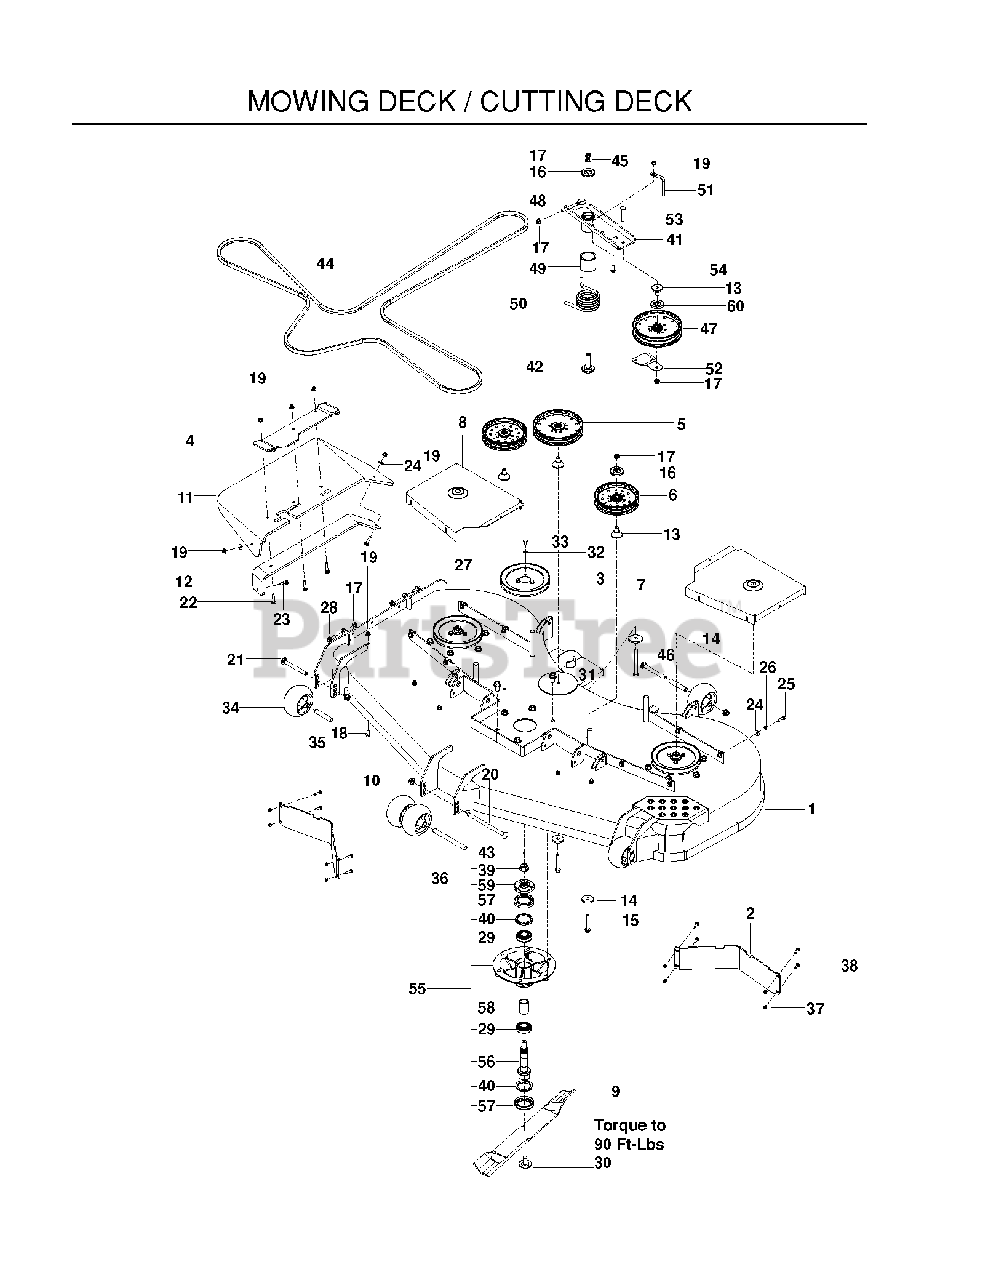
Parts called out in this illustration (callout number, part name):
1	DECK.SVC.W/DECALS.72.ORANGE.HU
2	BAFFLE, DIVERTER 72" BLACK
3	PULLEY - 7.50
4	BRKT - CHUTE MTG BLACK
5	PULLEY - 7" NARROW
6	PULLEY IDLER, 6" NARROW
7	SHIELD, BELT 72 R.H. ORANGE
8	SHIELD, BELT 72 LH ORANGE
9	BLADE OEM - 25"
10	NUT, 1/2-13 HEX FLG NYLOC ZD
11	CHUTE, DISCHARGE 60-72
12	BRKT - CHUTE SUPPORT BLACK
13	BEARING, IDLER ARM
14	SPINDLE WASHER
15	HHFS 3/8-16 X 2 3/4
16	DUST SHIELD
17	NUT 3/8-16 HEX FLG NYLOC ZD
18	HHFS 5/16-18 X 3/4
19	5/16-18 NYLOC FLANGE NUT
20	RHSNB 1/2-13 X 8 GR5 ZD
21	RHSNB 1/2-13 X 4.75 GR5 ZD
22	RHSNB 5/16-18 X 1-1/2 GR 5 ZD
23	BOLT, CARRIAGE 5/16X1-1/4
24	WASHER 5/16 FLAT
25	HCS 5/16C X 1
26	WASHER 5/16 LOCK
27	U-CLIP 5/16-18 NUT RETAINER
28	HHFS 3/8-16 X 1 GRD 5 ZD
29	BEARING - 206KRR8
30	BLADE BOLT/WASHER
31	HHFS 1/2-13 X 1 GR5 ZD
32	WASH 5/16 DISC SPRING ZD
33	HCS 5/16-18 X 1/2 GR 5 ZD
34	ROLLER, GAUGE .635 BORN
35	TUBE, ROLLER AXLE
36	TUBE, ROLLER AXLE LONG
37	RP_NUT 1/4-20 NYLOC
38	1/4-20X3/4 CARR BLT
39	NUT FLANGE 3/4-16
40	V-RING, 55MM
41	ASSY, IDLER ARM, PZ
42	BEARING, IDLER PIVOT
43	ZERK
44	BELT, "B", 201
45	WASHER, 3/8 THICK
46	HCS 3/8-16 X 4-1/2 GR 8 ZD
47	PULLEY - IDLER 7"
48	EYE BOLT, 3/8 X 4"
49	SPACER, IDLER PIVOT
50	SPRING, TORSION, IDLER
51	BELT KEEPER
52	BELT.GUIDE.BLACK
53	CARRIAGE BOLT 3/8-16 X
54	RHSSNB 5/16C X 1.0
55	SPINDLE ASM. 10"
56	SHAFT - SPINDLE
57	CUP - DEBRIS
58	SPACER - BEARING
59	HUB - PULLEY
60	SHIELD, DUST
